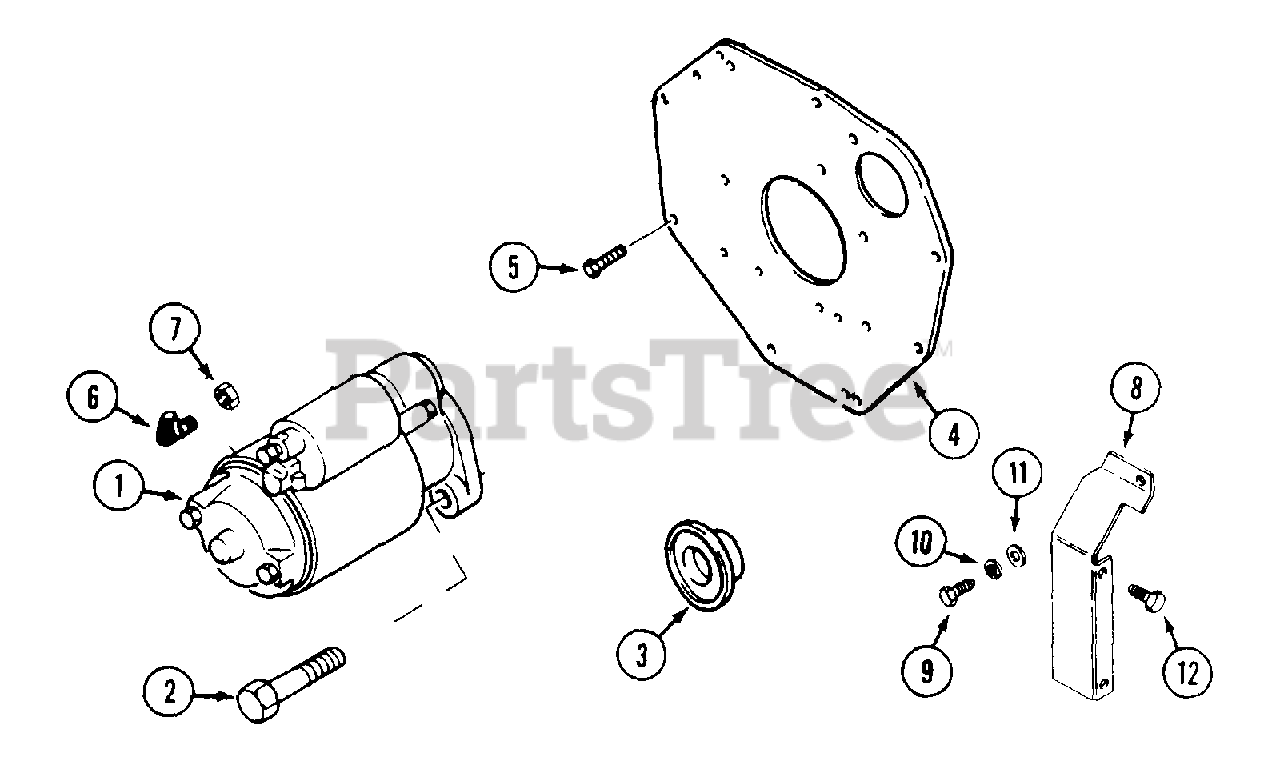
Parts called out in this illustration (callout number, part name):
1	STARTER - repairs below
2	SCREW
3	SEAL - rear
4	PLATE
5	SCREW
6	INSULATOR - terminal
7	NUT - M8
8	SHIELD - flywheel R.H.
9	BOLT - M8 - 1.25
10	LOCKWASHER - 5/16"
11	WASHER - 5/16" x 3/4"
12	BOLT - 1/4" - 20 x 1/2" flange lock
